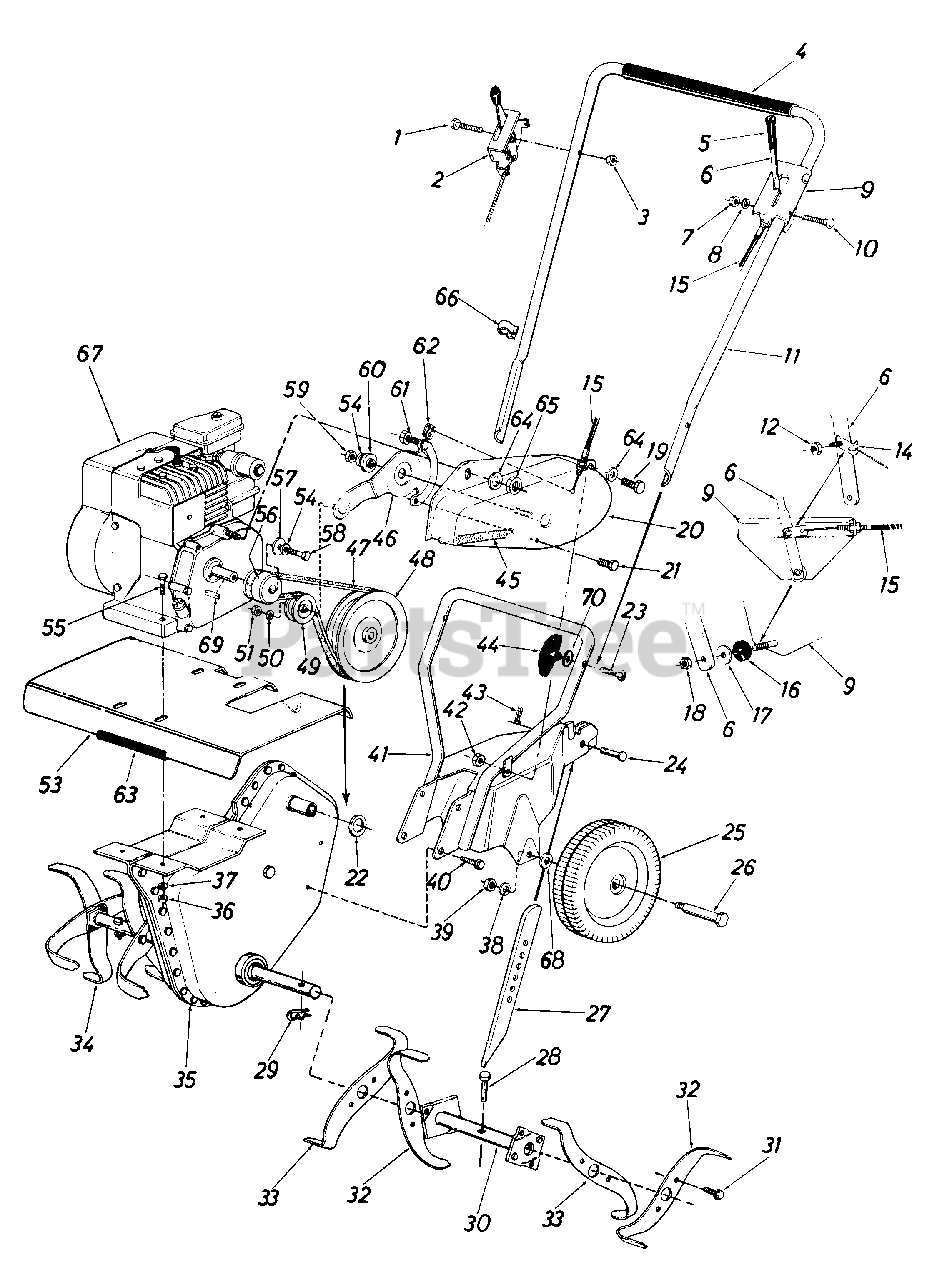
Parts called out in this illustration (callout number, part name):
1	Hex Bolt 1/4-20 x 1.50" Lg.
2	Throttle Control Ass'y. Comp.
3	Hex Cent. L-Nut 1/4-20 Thd.
4	Grip - 12" Lg.
5	Handle Grip
6	Clutch Handle Ass'y.
7	Hex Cent. L-Nut 1/4-20 Thd.
8	Fl-Wash. 1/4" I.D. x .50" O.D. x .063
9	Clutch Handle Brkt. Ass'y.
10	Carr. Bolt 1/4-20 x 1.25" Lg.
11	Upper Handle
12	Hex Cent. L-Nut 1/4-20 Thd.
15	Clutch Cable
16	Rubber Wash.
17	Fl-Wash. 1/4" I.D. x .75" O.D. x .063
18	Hex Cent. L-Nut 1/4-20 Thd.
19	Hex Bolt 1/4-20 x .50" Lg.
20	Belt Cover Ass'y.
21	Hex Wash. Hd. Tap Scr. 1/4 x .50"
22	Fl-Wash. .52 I.D. x 1.00 O.D. x .050
23	Curved Hd. Bolt 5/16-18 x 1.75" Lg.
24	Clevis Pin
25	Wheel Ass'y.
26	Shoulder Bolt
27	Depth Bar
28	Clevis Pin .31 Dia. x 1.50" Lg.
29	Hairpin Cotter
34	Tine Ass'y. Comp.
35	Chain Case Ass'y. Comp.
36	Hex Nut 5/16-18 Thd.
37	L-Wash. 5/16" Scr.
38	L-Wash. 3/8" Scr. H.D.
39	Hex Cent. L-Nut 3/8-16 Thd.
40	Hex Wash. SF-Tap Scr. 5/16-18 x .50" Lg.
43	Intern. Cotter Pin
44	Hand Knob
45	Extension Spring .60 O.D. x 4.88" Lg.
46	Idler Arm Ass'y.
47	Belt 3/8" x 29" Lg.
48	Chain Case Pulley 5 1/2 x 1/2"
49	Fl-Idler 2"
50	L-Wash. 5/16" Scr.
51	Hex Nut 3/8-24 Thd.
55	Hex Bolt 5/16-18 x 1.50" Lg.
56	Engine Pulley 3/8 V x .7525 I.D. x 2" O.D.
57	Fl-Wash. .385 I.D. x 1.00" O.D. x .135
58	Hex Bolt 3/8-24 x 1.00" Lg.
59	Hex Nut 5/16-18 Thd.
60	Shld. Spacer .50" Dia. x .133
61	Hex Cent. L-Nut 1/4-20 Thd.
63	Trim Strip - 4"
64	Fl-Wash. .281" I.D. x .500" O.D. x .063
65	Hex Cent. L-Nut 1/4-20 Thd.
66	Cable Clip
67	Engine
68	Bell-Wash.
69	Square Key 3/16 x 3/4" Lg.
70	Belleville Washer
04765-0637	TINE SHIELD - POWDER BLACK (0637)
